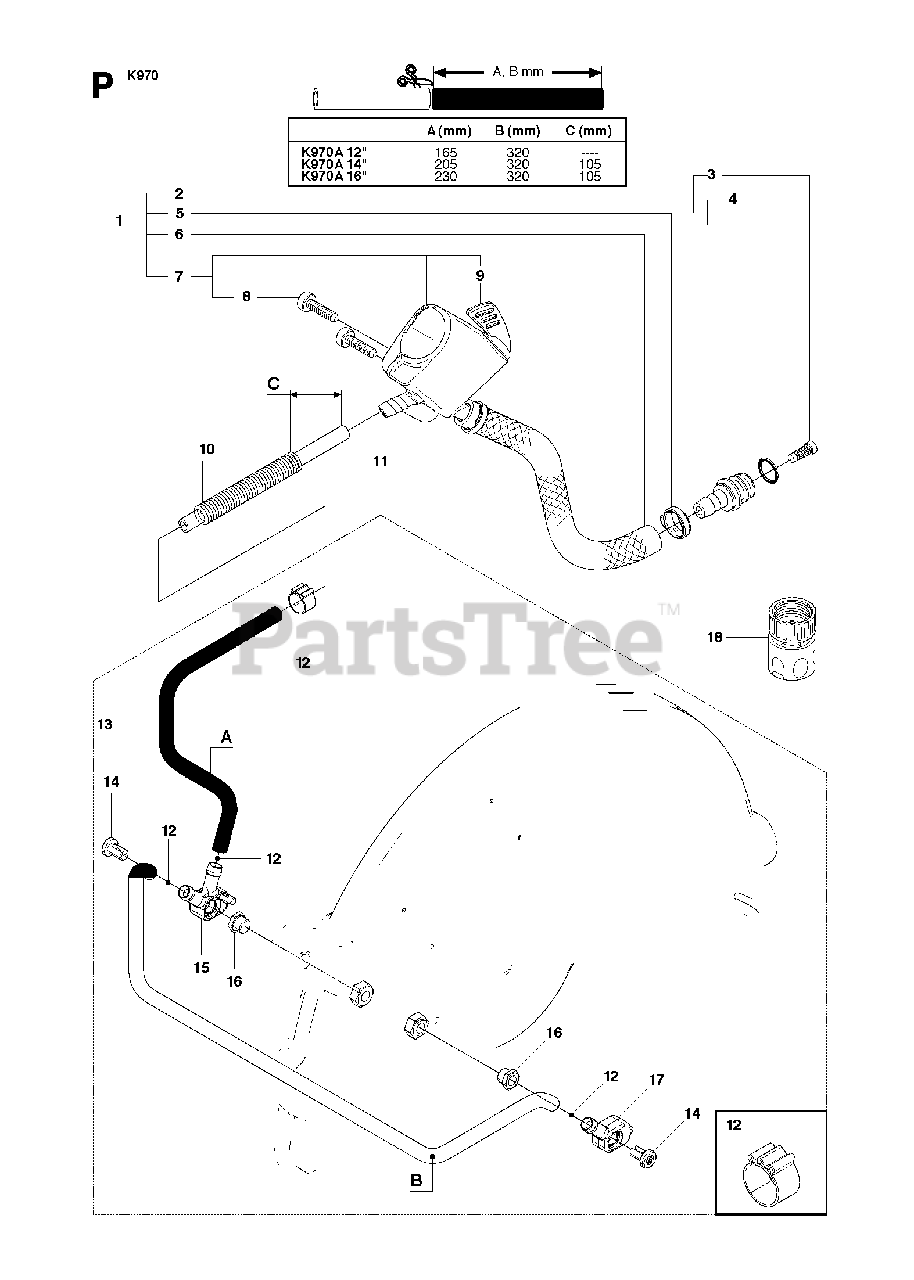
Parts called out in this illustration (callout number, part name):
5	HOSE CLAMP
8	SCREW ITXSCT
9	VALVE SPINDLE
10	PROTECTIVE SPRING
13	HOSE
14	SCREW ITXSCM
